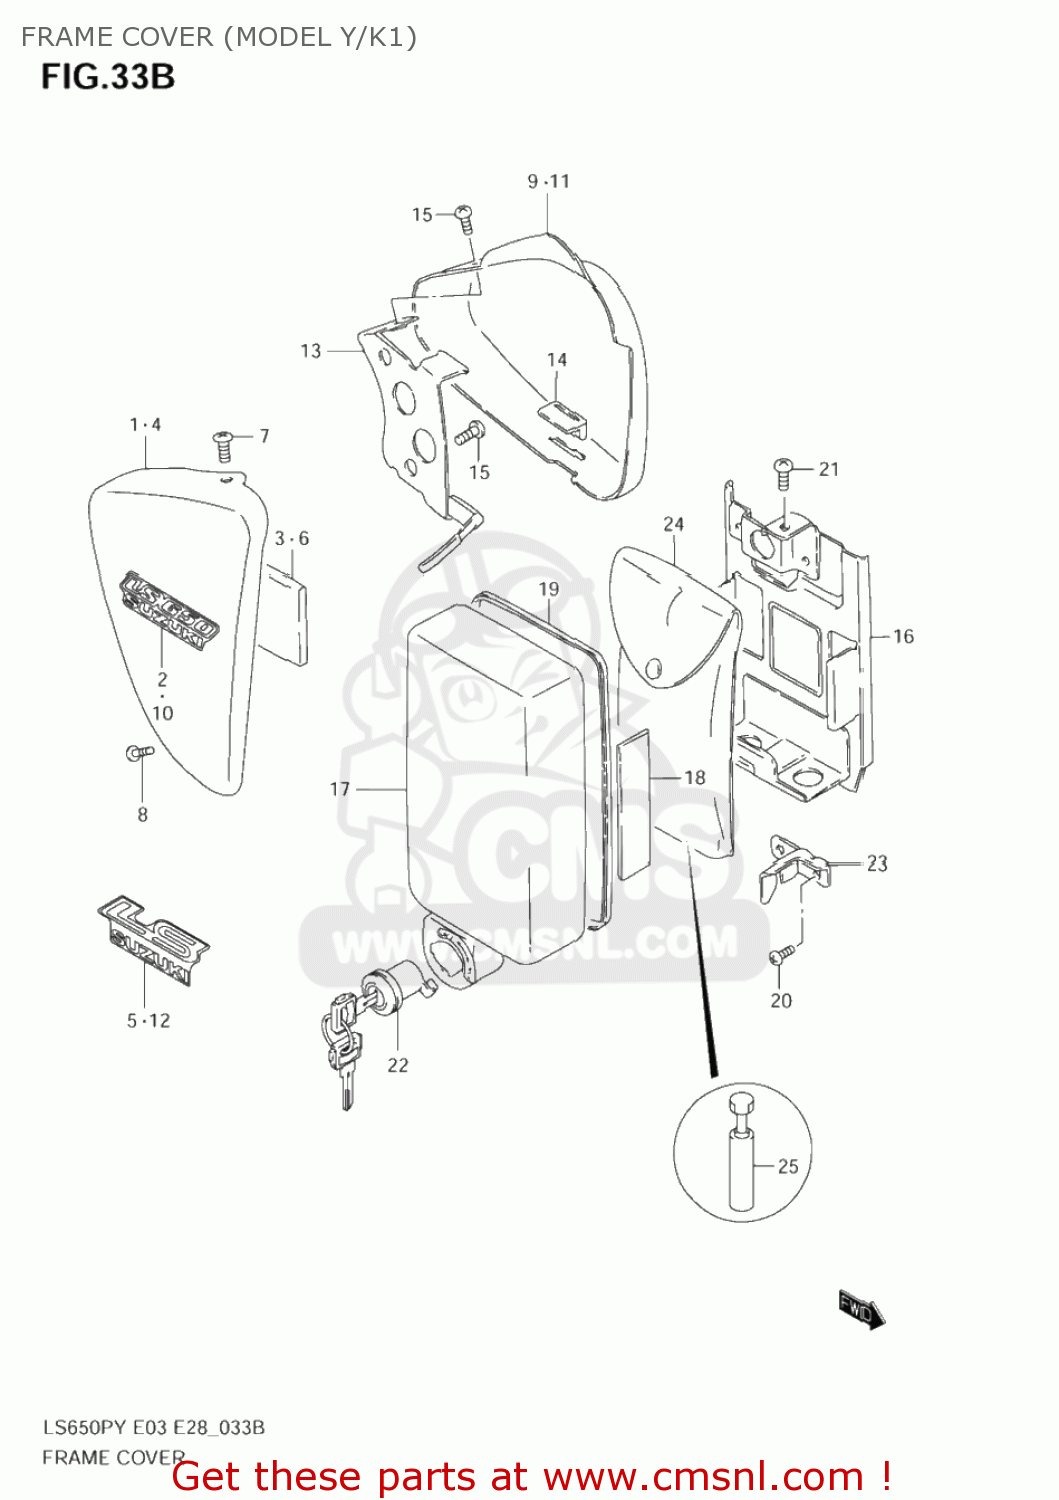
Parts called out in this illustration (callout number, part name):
1	COVER ASSY,FRAME,R(GREEN)
2	EMBLEM,FUEL TANK
3	PAD
4	COVER, FRAME RH (BLACK)
5	EMBLEM
6	PAD
7	SCREW
8	SCREW
9	COVER ASSY,FRAME,L(GREEN)
10	EMBLEM,FUEL TANK
11	COVER ASSY,FRAME,L(BLACK)
12	EMBLEM
13	BRACKET,FRAME COVER,L
14	CUSHION,FRAME COVER
15	SCREW
16	HOLDER,TOOL
17	COVER COMP,TOOL HOLDER
18	PROTECTOR(80X80X2)
19	MOLDING
20	SCREW
21	SCREW
22	LOCK SET,TOOL HOLDER
23	PLATE,TOOL HOLDER LOCK
24	TOOL ASSY
25	GAUGE ASSY,TENSION
